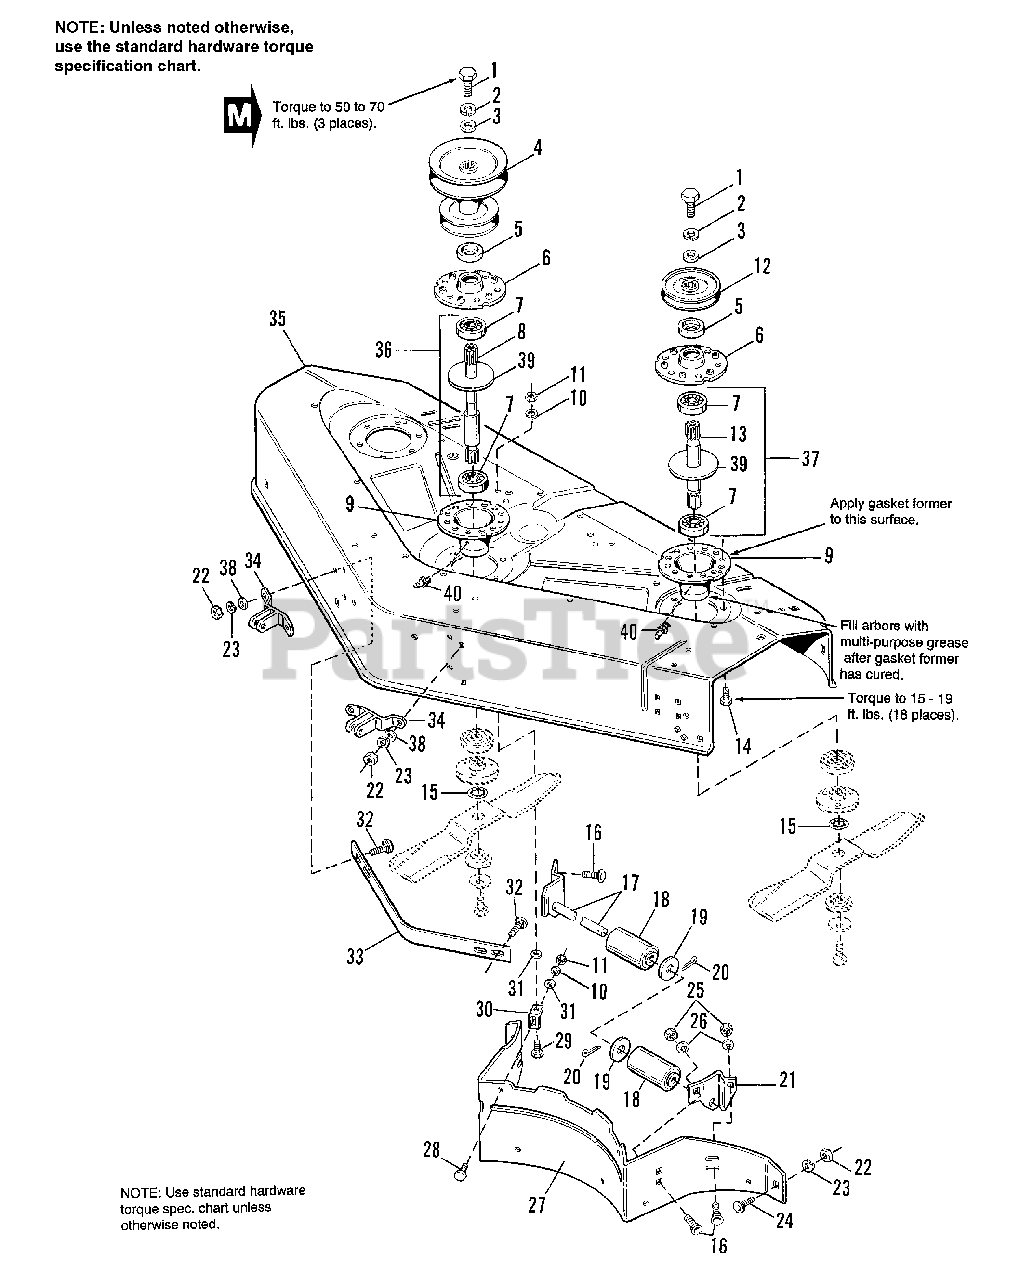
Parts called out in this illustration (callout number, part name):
1	CAPSCREW, Hex Hd., 7/16-14 x 1-1/4
2	LOCKWASHER, 7/16
3	WASHER, 29/64 x 1-1/4 x 1/4
4	PULLEY ASSEMBLY
5	SHIELD, Bearing Upper, Arbor
6	HOUSING, Arbor, Top
8	SHAFT.Arbor, Center
9	HOUSING, Arbor Bottom
10	LOCKWASHER, 1/4
11	NUT, Hex, Full, 1/4-20
12	PULLEY ASSEMBLY, Deck Drive
13	SHAFT, Arbor, Side
14	CAPSCREW, Hex Washer Hd, Taptite, 5/16-18 x 3/4
15	RING, Self-Locking
16	CARRIAGE BOLT, 5/16-18 x 3/4
17	BRACKET & SHAFT ASSEMBLY
19	WASHER, 21/32
20	PIN, Cotter
21	BRACKET, Roller, L.H.
22	NUT, Hex, Full, 3/8-16
23	LOCKWASHER 3/8
24	CARRIAGE BOLT, 3/8-16 x 1
25	NUT, Hex, Full, 5/16-18
26	LOCKWASHER, 5/16
27	BAFFLE, 48" Mower
27	BAFFLE, 42" Mower
28	CAPSCREW, Hex Hd, 1/4-20 x 5/8
29	CAPSCREW, Thread Forming, 1/4-20 x 3/4
30	CLIP,. Baffle
31	WASHER, Plain, 9/32
32	CARRIAGE BOLT, 3/8-16 x 1-1/4
33	BAR, Reinforcement
34	BRACKET ASSEMBLY, Front
35	HOUSING, 42 Mower (Orange)
35	HOUSING, 48 Mower (Orange)
35	HOUSING, 42 Mower (Black)
35	HOUSING, 48 Mower (Black)
36	SHAFT & BEARING ASSEMBLY, Center
37	SHAFT & BEARING ASSEMBLY, Side
38	WASHER, 13/32 I.D.
39	GASKET, Foam
40	FITTING, Grease
